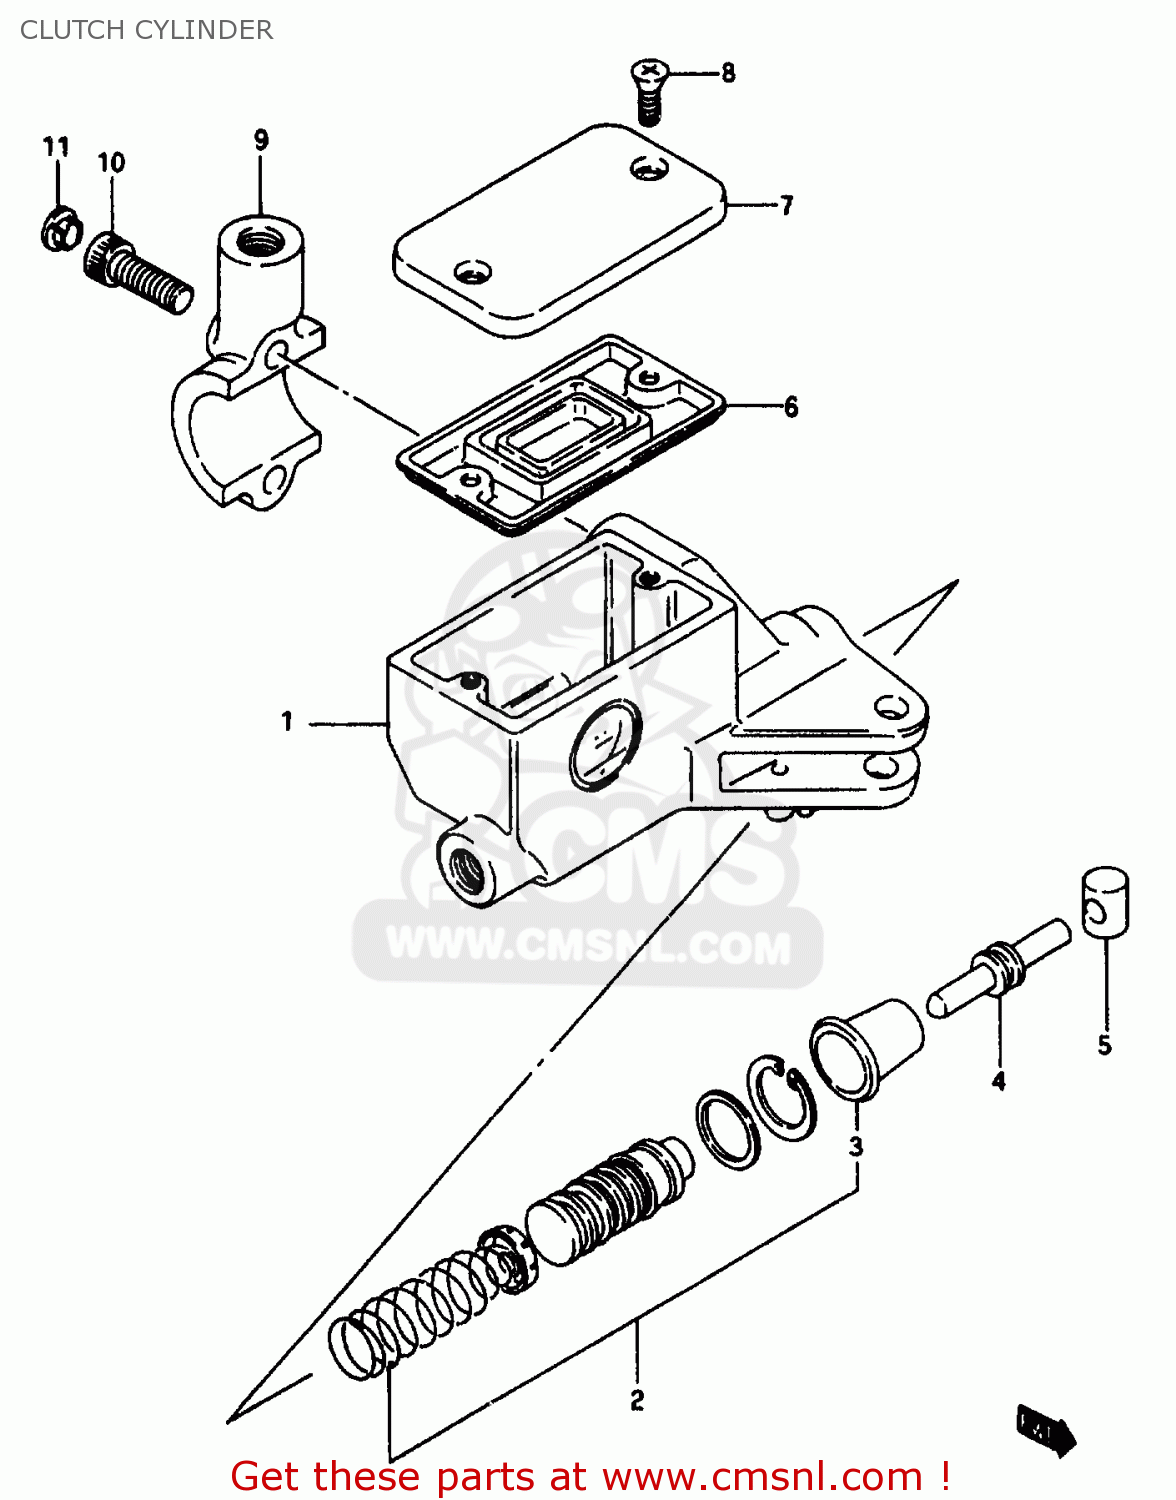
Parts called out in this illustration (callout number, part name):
1	CYLINDER ASSY, CLUTCH MASTER
2	PISTON & CUP SET
3	BOOT
4	PUSH ROD
5	BUSH
6	7
7	CAP
8	SCREW
9	HOLDER
10	BOLT
11	CAP(OD:10)
